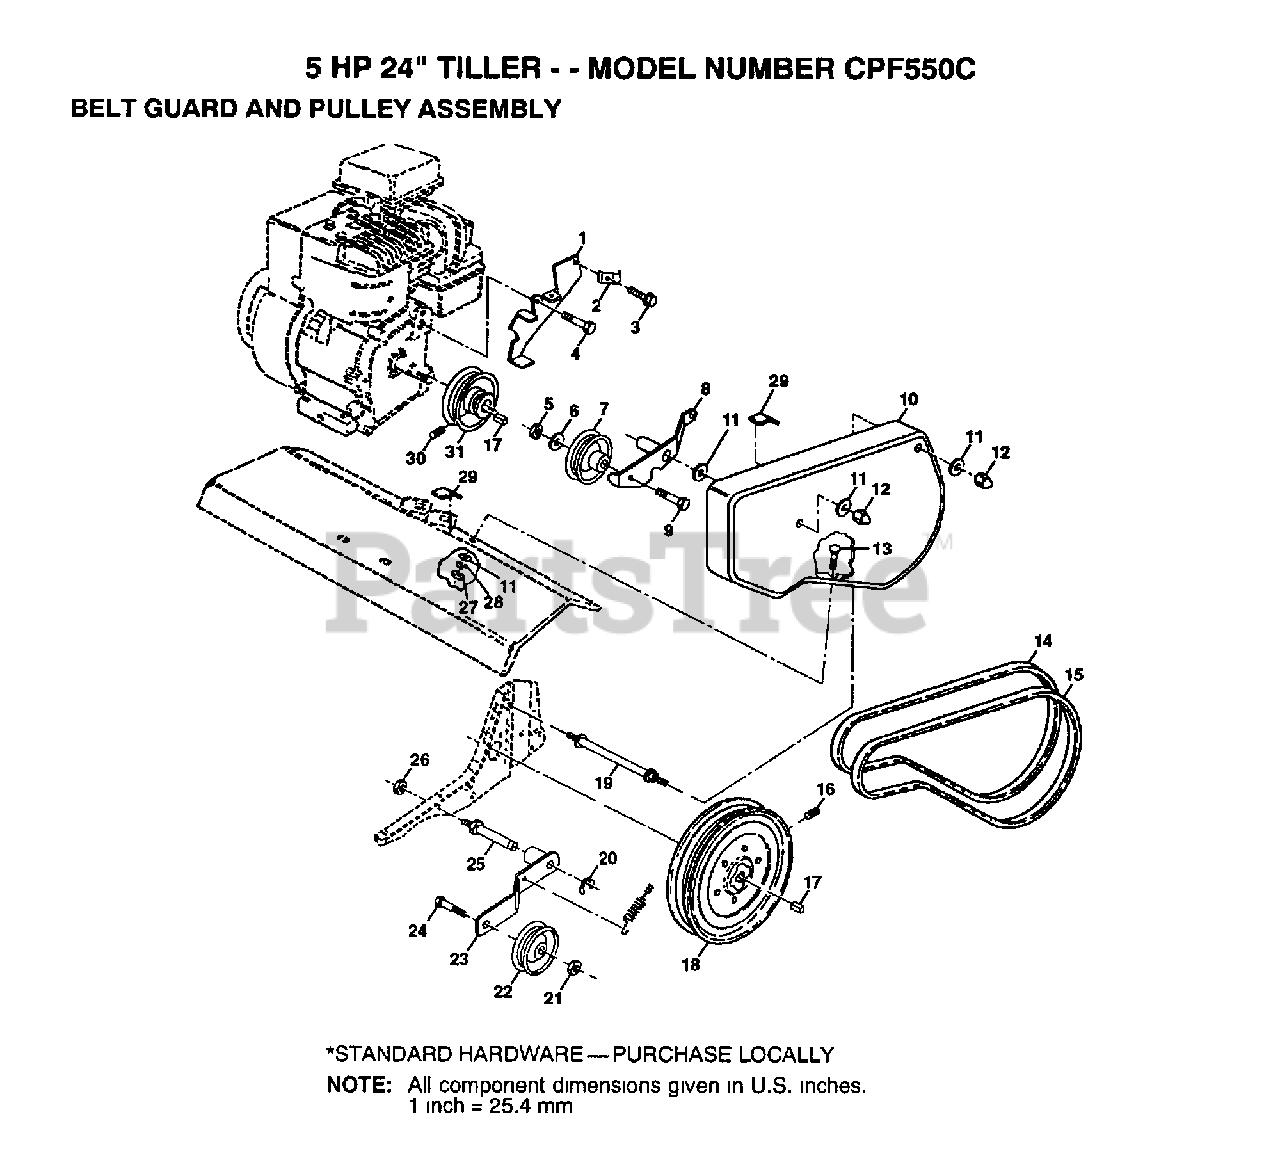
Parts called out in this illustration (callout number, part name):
2	CONDIUT CLIP T
5	NUT.HEX.3/8-16UNC
6	WASHER
7	PULLEY W/SPACER
8	ARM.ASM.REV.IDLER
11	WASHER
12	NUT-CAP TI
13	BOLT T
14	BELT-V
16	SET SCREW
17	KEY T
19	BOLT TI
20	KLIP RING TI
21	NUT
23	IDLER ARM TI
25	SHAFT IDLER TI
26	JAM NUT TI
28	LOCKWASHER
29	PAD IDLER TI
30	SET SCREW
31	ENGINE PULLEY TI
